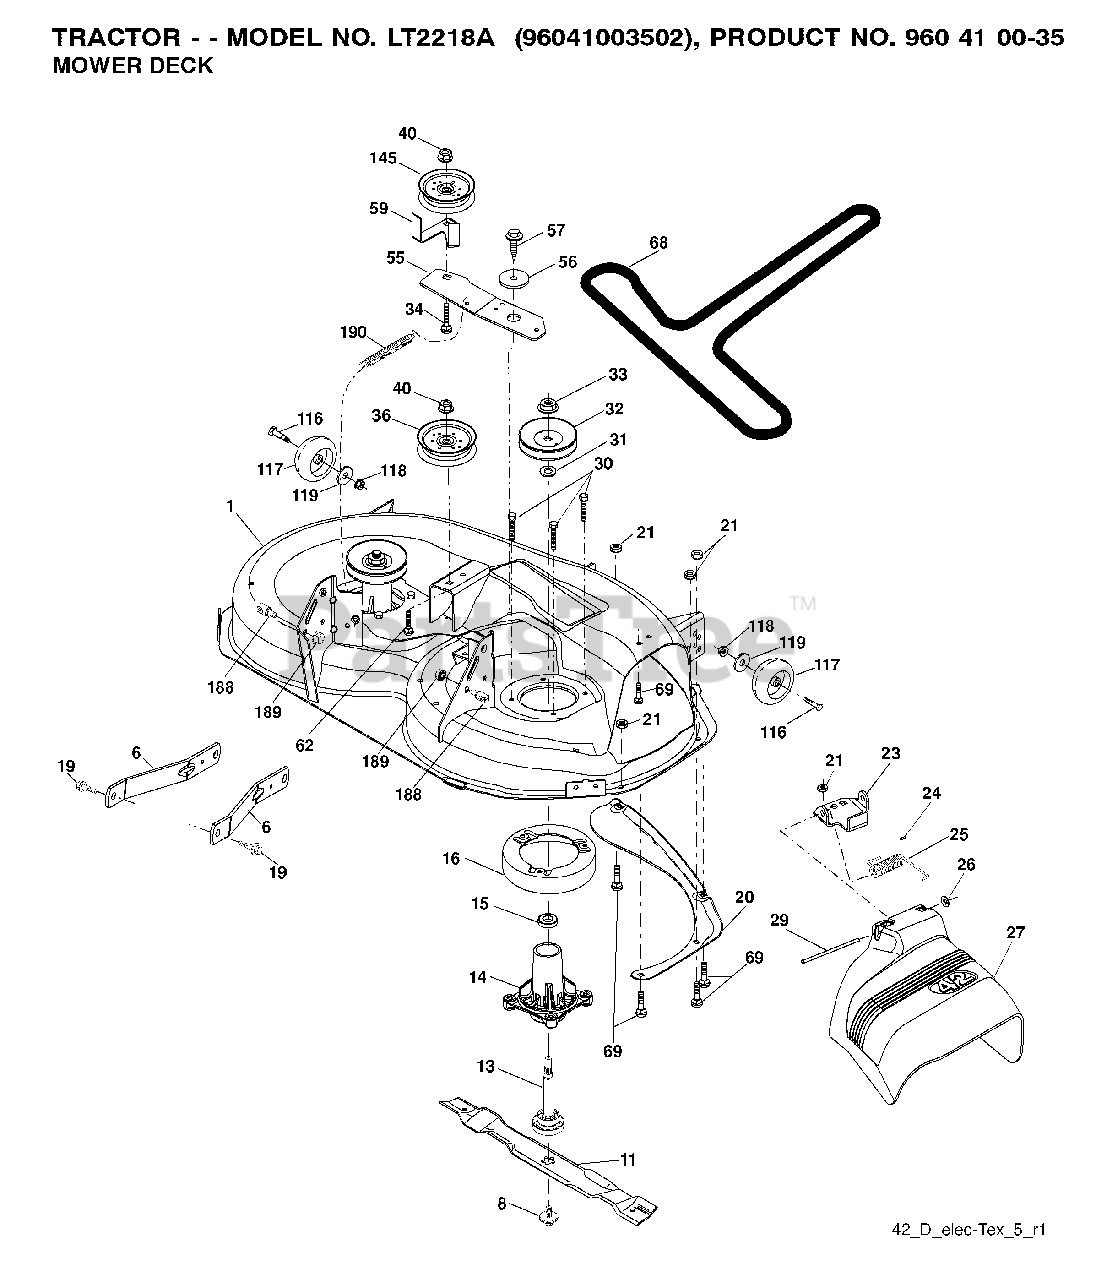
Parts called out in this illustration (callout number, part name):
1	DECK.WELDMENT.42"
6	ARM.SUSPENSION.MOWER.R
8	BOLT.WASHER.ASM.7/16-2
11	42" HI-LIFT BLADE
13	SHAFT.ASM.MDRL.N/GREASE.38
14	HOUSING MANDREL
16	STRIPPER, MWR ROUND
19	BOLT.SHOULDER
20	BAFFLE.VORTEX
21	LOCKNUT
23	BRKT.DEFLECTOR.38"2005+
24	CAP-SLEEVE LT
25	SPRING.TORSION.DEFLECT
26	NUT PUSH M
29	ROD.HINGE
30	SCREW, WASHER HEAD
31	WASHER.SPACER.MANDREL
32	PULLEY/MANDREL
33	NUT.FLANGE.LOCK.TOP
34	BOLT.3/8-16X1.50
36	PULLEY.IDLER.48"PRIMARY
40	NUT LOCK FLG 3/8-16 UNC
46	SCREW.1/4-20X5/8
55	IDLER.ARM
56	SPACER.RETAINER
57	SCREW 3/8-16X1
59	GUARD, BELT
62	BOLT
68	BELT V SECONDARY
69	BOLT
117	WHEEL.GAGE.HALF.SPOKED
118	LOCKNUT
119	WASHER
145	PULLEY.IDLER.2006
188	STUD.FASTNER.W/ANTI-ROTATE
189	NUT LOCK HEX FLANGE 5/16-18
190	SPRING.MOWER.DRIVE.ELECTRIC
199	SCREW 3/8-16X1/2
